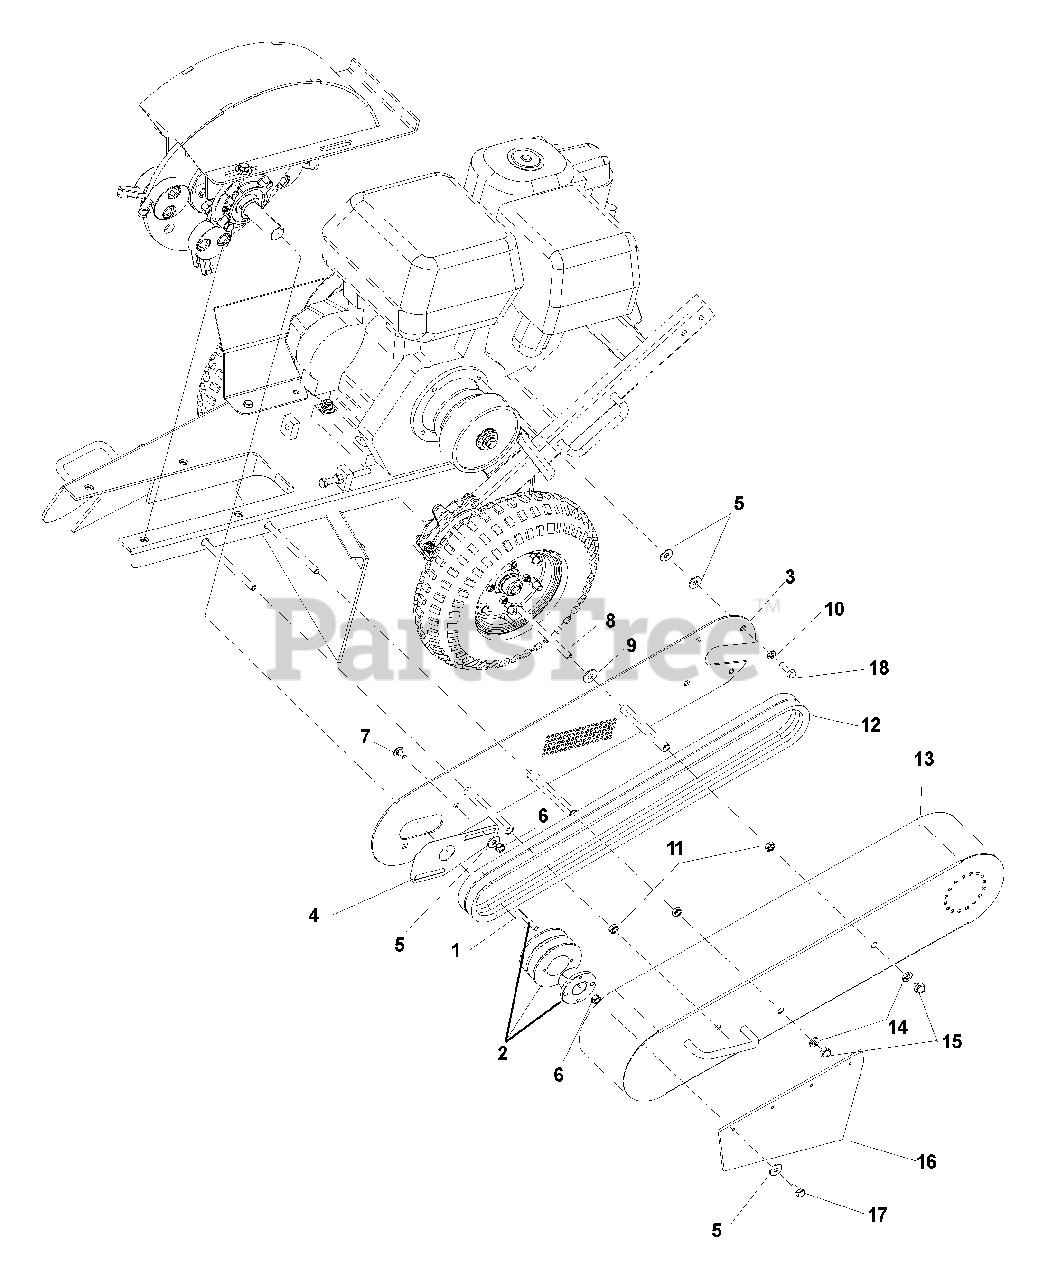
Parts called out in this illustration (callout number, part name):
1	KEY 1/4 SQ X 2
2	PULLEY, TAPERLOCK, 2V
3	BELT GUARD BACK
4	PLATE, COVER
5	WASHER 5/16, FLAT
6	NUT 5/16C, CENTER LOCK
7	RHSNB 5/16-18 X 5/8, GR5
8	HCS 3/8-16 X 5 1/2, GR5
9	WASHER 3/8 FLAT
10	LOCKWASHER 3/8
11	NUT 3/8-16, JAM
12	V-BELT, "B" SECT. SET OF 2
13	COVER, BELT GUARD
14	LOCKWASHER 3/8
15	NUT 3/8-16, ACORN
16	DEFLECTOR, NEOPRENE, LEFT SIDE
17	HCS 5/16-18 X 3/4, GR5
18	HCS 5/16-24 X 1, GR5
